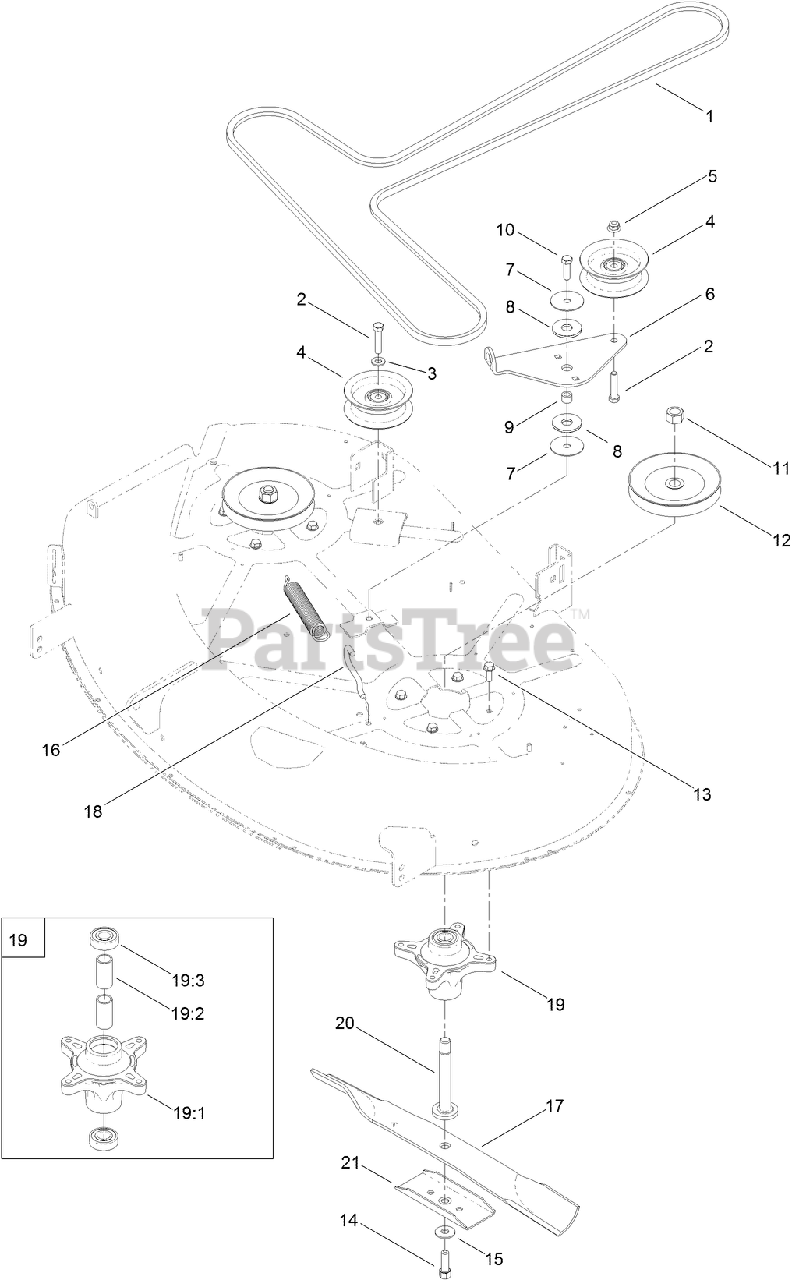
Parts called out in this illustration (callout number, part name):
1	V-BELT
2	SCREW-HH
3	WASHER-FLAT
5	NUT-HF, NI
6	ARM-IDLER
7	WASHER
8	WASHER-FRICTION, COMPOSITE
9	SPACER
10	SCREW-HH
11	NUT-HEX
12	PULLEY
13	SCREW-TAPTITE
14	SCREW-HH
15	WASHER-BELLEVILLE
16	SPRING-EXTENSION
18	HOOK-RETURN, SPRING
19	SPINDLE ASM
19:2	SPACER
20	SHAFT-SPINDLE
21	STIFFENER-BLADE
